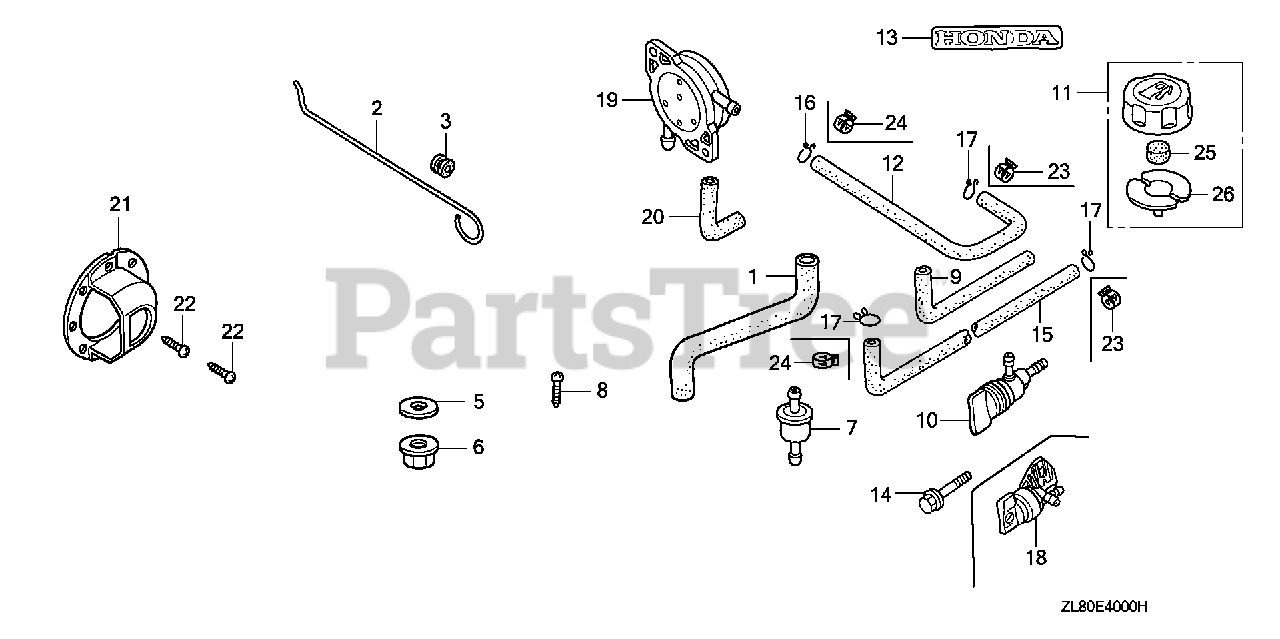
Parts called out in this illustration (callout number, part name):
2	ROD, CHOKE CONTROL
3	GROMMET, CHOKE ROD
6	NUT, FLANGE (6MM)
7	STRAINER, FUEL
9	RUBBER, SUPPORTER (107MM)
10	PETCOCK ASSY.
11	CAP ASSY., FUEL TANK
12	TUBE, FUEL
13	MARK, HONDA
14	BOLT, FLANGE (6X12) (CT200)
15	BULK HOSE, FUEL (4.5X3000) (4.5X140)
16	CLIP, TUBE (B8)
17	CLIP, TUBE (C9)
18	PETCOCK ASSY.
25	SPONGE, FUEL CAP BREATHER
26	GASKET, FUEL CAP
